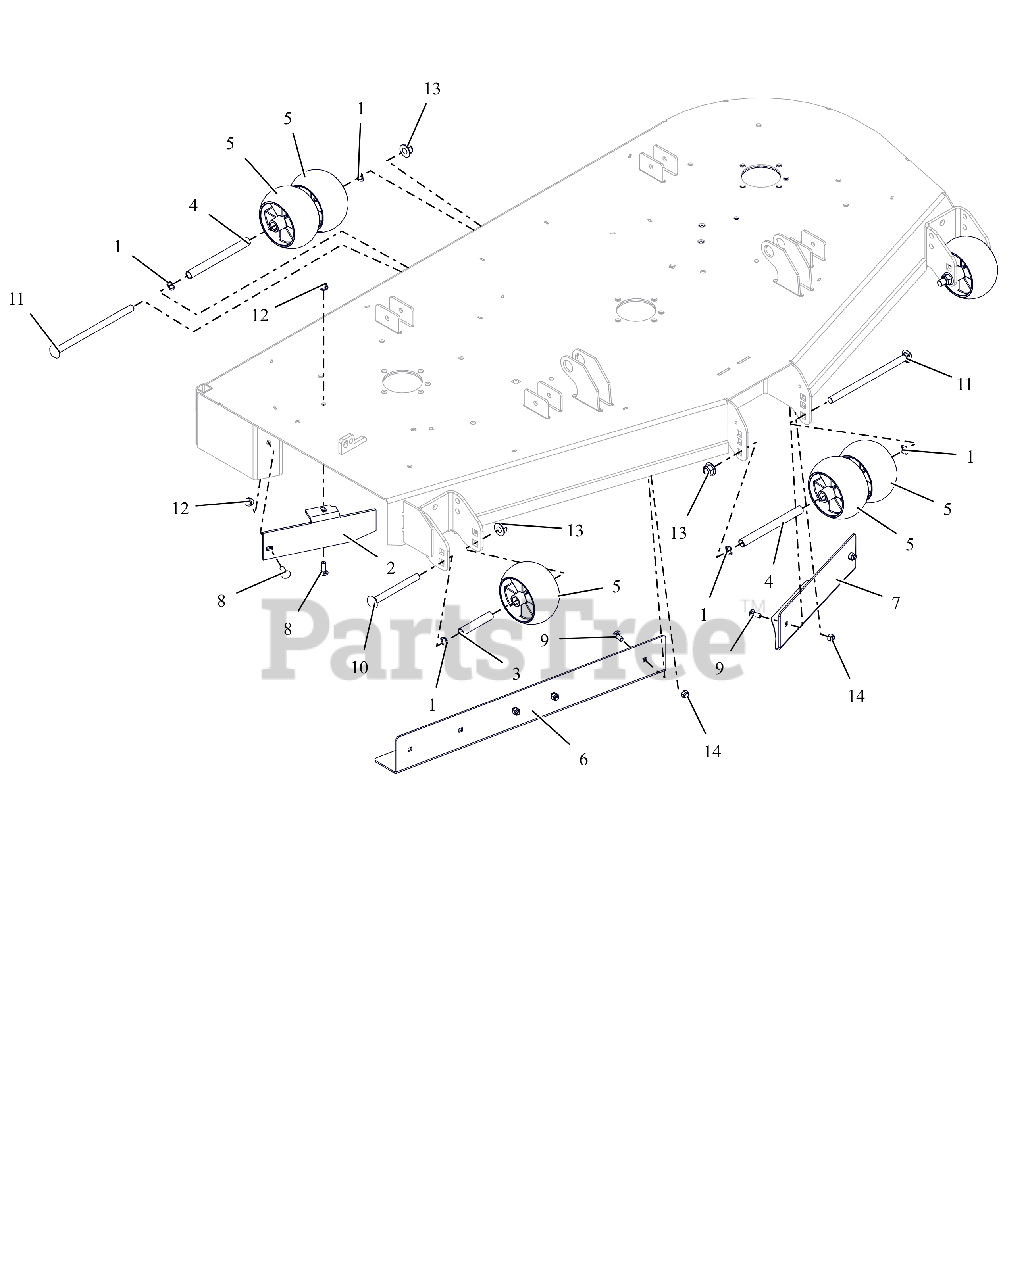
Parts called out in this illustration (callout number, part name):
1	WAVE WASHER .531X.781X.125FH
2	60" DISCHARGE BAFFLE - RED
3	SPACER, .510X.625X3.35
4	SPACER, .510X.625X6.50
5	ANTI-SCALP WHEEL - 5X3 CTR
6	BAFFLE, 60" RH VACUUM (RED)
7	BAFFLE, 60" LH VACUUM (RED)
8	BLT,RHSN .31-18X1.00 G5 ZCC
9	BLT,RHSN .31-18X.75 G5 ZCC
10	BLT, RHSN .50-13X5.00 G5 ZCC
11	BLT, RHSN .50-13X8.50 G5 ZCC
12	NUT,NYL-FLG .31-18 GF ZCC
13	NUT,NYL-FLG .50-13 GF ZCC
14	NUT,NYL .31-18 G5 ZCC
